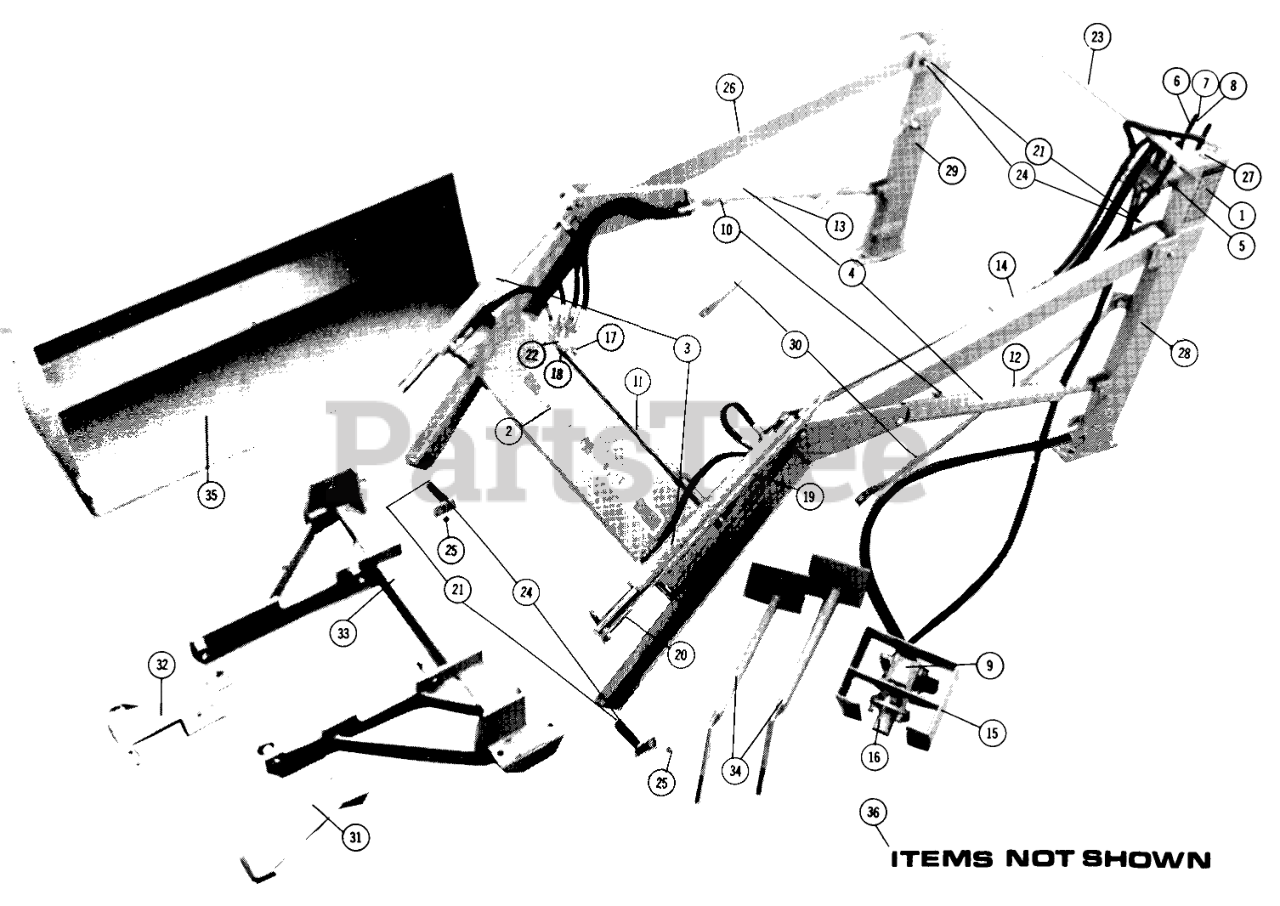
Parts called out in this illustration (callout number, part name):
1	Decal, Caution
2	Decal, Wheel Horse
3	Tilt Cylinder
4	Lift Cylinder
5	Control VaIve
6	Handle Linkage
7	Black Vinyl Cover
8	Valve Handle (with Cover)
9	Hydraulic Pump
10	52014/15/90A RER 34
11	Self Tapping Screw
12	Hydraulic Cylinder Tube LH
13	Hydraulic Cylinder Tube RH
14	Hydraulic Line
15	Pump Mounting Bracket
16	Pump Coupling
17	Hydraulic Line Hold Down
18	Hydraulic Line Bracket
19	Bucket Guide Tube
20	Bucket Guide Rod
21	Grease Fitting
22	Foam Cushion
23	Stabilizer Bar
24	Lift Frame Pin
25	Lift Frame Pin Bushing
26	Lift Frame Assembly
27	Breather Cap
28	Left Upright
29	Right Upright
30	Brace Arm
31	Front Mounting Bracket (Left)
32	Front Mounting Bracket (Right)
33	Underframe Assembly
34	Dismount Stand
35	48 in. (122 cm) Heavy Duty Bucket
36	Ballast Box
